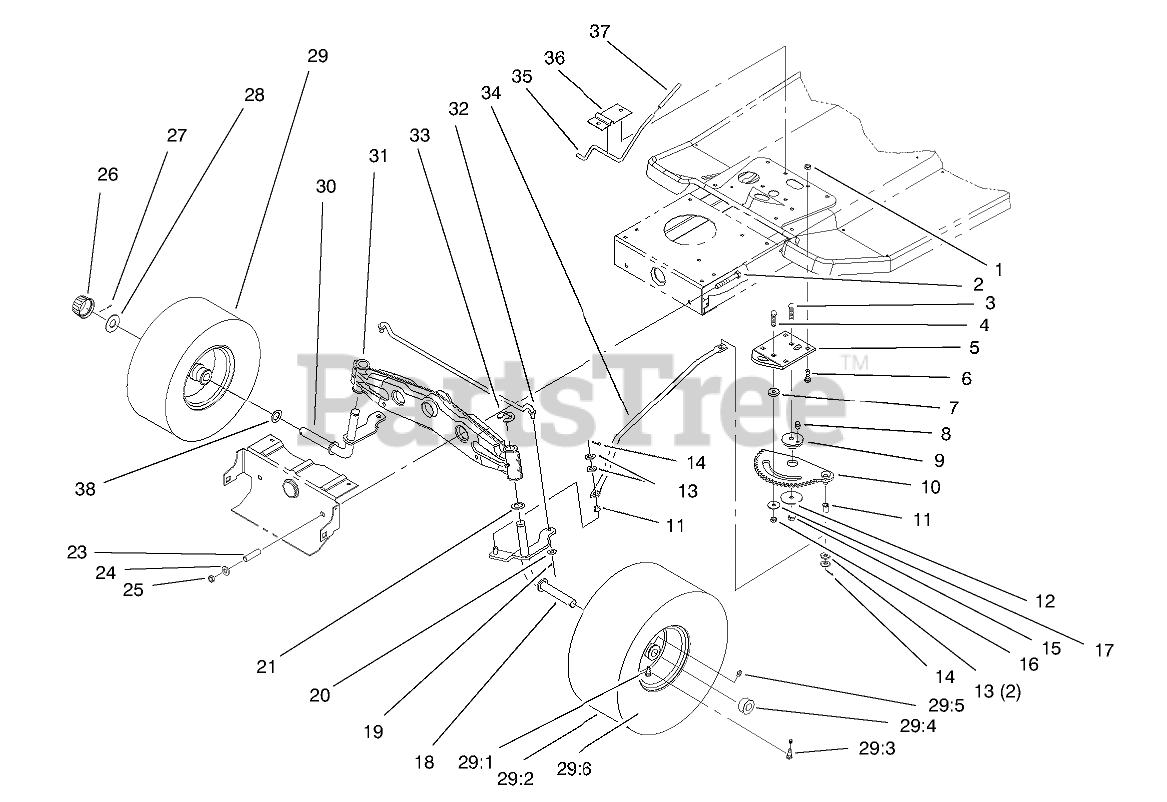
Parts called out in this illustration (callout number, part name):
1	NUT-LOCK, NI
2	SCREW-HH
3	SCREW-CARR
4	SCREW-CARR
5	BRACKET-RACK, STEERING
6	BOLT-CARR
7	SPACER-RACK, STEERING
8	FITTING-GREASE
9	BUSHING-ECCENTRIC
10	RACK-STEERING
11	BUSHING-FLANGED, NYLON
12	WASHER-BEARING
13	WASHER-FLAT
14	PIN-COTTER
15	NUT-LOCK, NI
16	NUT-LOCK, NI
17	WASHER-PIVOT
18	LH SPINDLE ASM
19	PIN-COTTER
20	WASHER-FLAT
21	WASHER-THRUST
23	SPACER
24	WASHER-FLAT
25	NUT-LOCK, NI
26	CAP-HUB
27	PIN-COTTER
28	WASHER-PLAIN
29	Front Wheel & Tire
29:1	RIM ASM
29:2	TIRE 15 X 6.00 X 6
29:3	STEM-VALVE
29:4	BEARING-WHEEL
29:5	FITTING-GREASE
29:6	TUBE-INNER
30	RH SPINDLE ASM
31	FRONT AXLE ASM
32	TIE ROD-STEERING
33	E-RING
34	LINK-DRAG
35	ROD-BRAKE, PARKING
36	BRACKET-PARKING BRAKE
37	GRIP-BRAKE, PARKING
38	WASHER-THRUST
